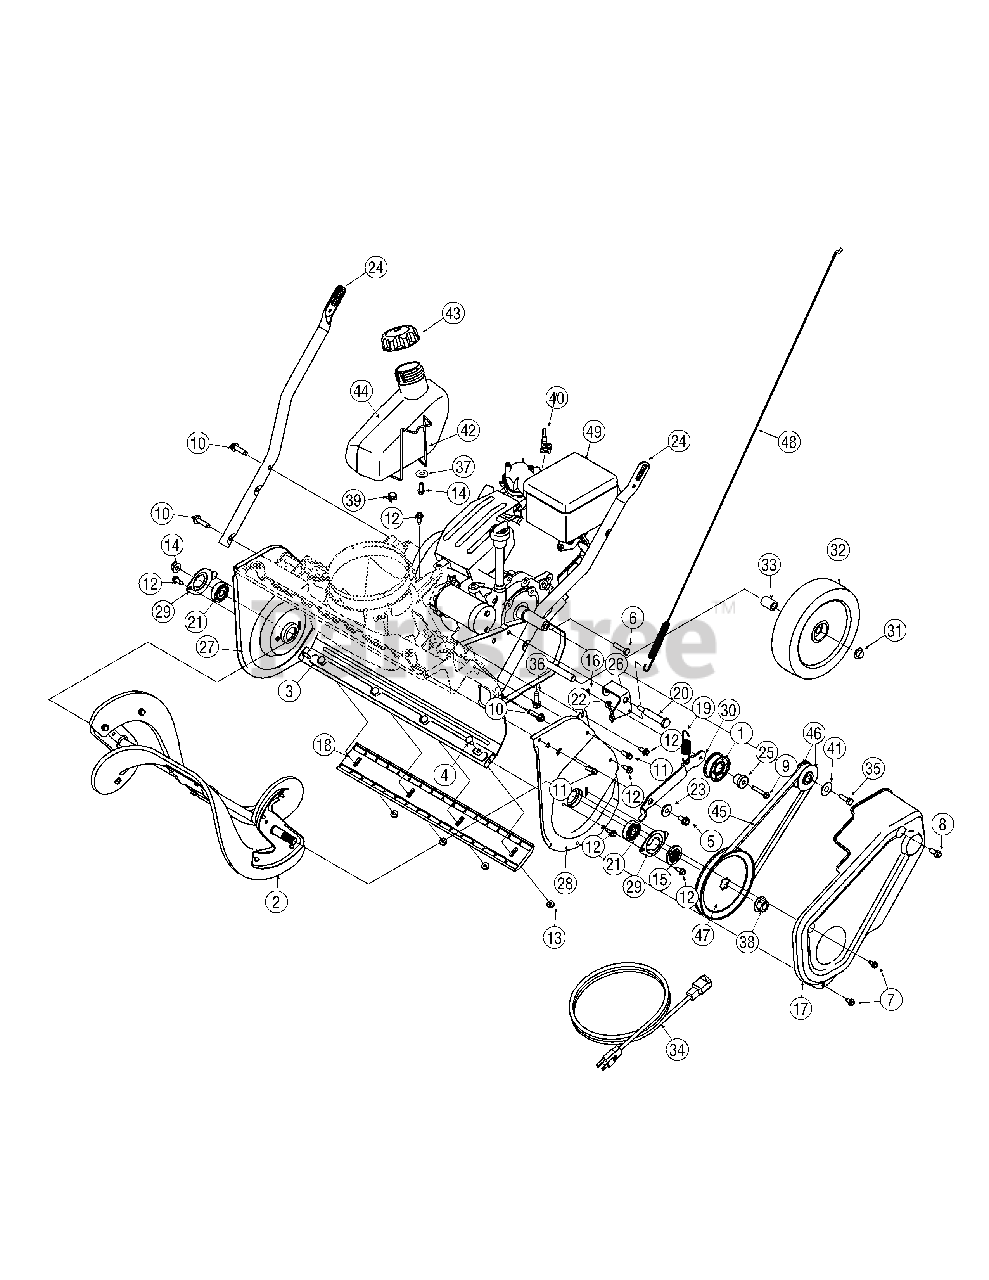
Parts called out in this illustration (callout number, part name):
1	Idler Pulley Assembly
2	Auger Assembly Complete
2	Auger Assembly Axle w/o paddles and center auger bracket
2	Rubber Auger Paddle Kit
2	Center Auger Bracket
2	Hex Washer Screw 1/4-20 x.750
3	Frame Assembly
4	Carriage Screw, 1/4-20 x .62
5	Hex Washer Screw, 5/16-18 x .750
6	Hex Screw, 5/16-24 x 1.25
7	Hex Washer Screw, 1/4-20 x .500
8	Hex Lock Screw, 5/16-24 x .750
9	Hex Washer Screw, 1/4-20 x 1.500
10	Hex Washer Screw, 5/16-18 x 1.250
11	Hex Washer Screw, 1/4-15 x .750
12	Hex Washer Screw, 1/4-20 x .625
13	Flange Lock Nut, 1/4-20
14	Flange Lock Nut, 3/8-16
15	Pulley Hub
16	Push Nut, .25 x .50
17	Belt Cover
18	Shave Plate
19	Extension Spring, .70 x 3.035
20	Shoulder Bolt, 5/16-24 x .496 x 2.18
21	Ball Bearing, .5000 x 1.375 x .4375
22	Drive Cable Wire Support
23	Shoulder Spacer
24	Lower Handle
25	Shoulder Spacer
26	Idler Cable Bracket
27	RH Side Plate
28	LH Side Plate
29	Bearing Cup
30	Idler Bracket
31	Push Cap, 1/2
32	Wheel, 8 x 1.7
33	Sleeve Spacer, .525 x .78 x 1.07
34	Extension Cord
35	Hex Lock Screw, 5/16-24 x .750
36	Hex Washer Screw, 3/8-16 x 1.000
37	Flat Washer, .265 x 1.000 x .030
38	Flange Nut, 7/16-20
39	Hose Clamp, .490
40	Choke Extension Lever
41	Flat Washer, .330 x 1.250 x .120
42	Gas Tank Wire Support
43	Fuel Cap
44	Fuel Tank
45	Belt, .500 x 35.06
46	Pulley Half, .625 x 2.25
47	Pulley, 1/2 x 6.00
48	Clutch Cable
49	Replacement Engine
